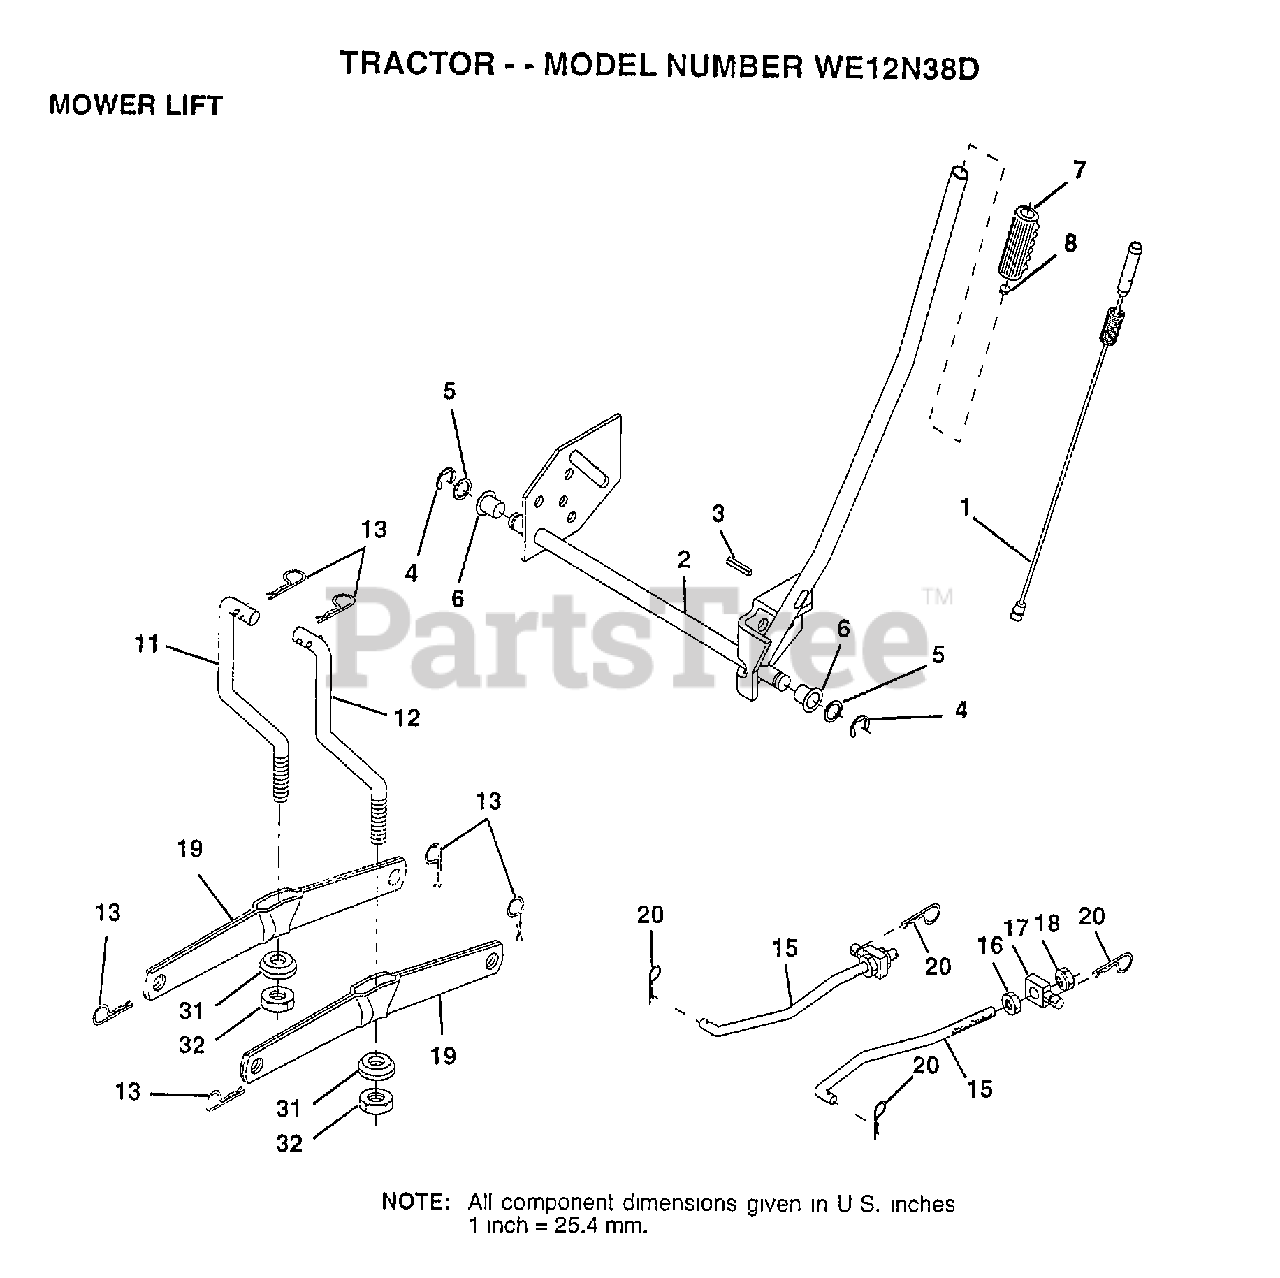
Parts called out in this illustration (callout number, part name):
1	WIRE ASM W.SPRING
2	SHAFT ASM.LIFT
3	PIN-GROOVE LT
5	WASHER
6	NYLON BEARING
7	GRIP
15	LINK.FRONT
16	NUT
17	TRUNION
18	NUT.LK.W/WSH.1/2.
19	ARM SUSP REAR
20	RETAINER.SPRING
31	BEARING PVT LH
32	NUT.CROWNLOCK.3/8
